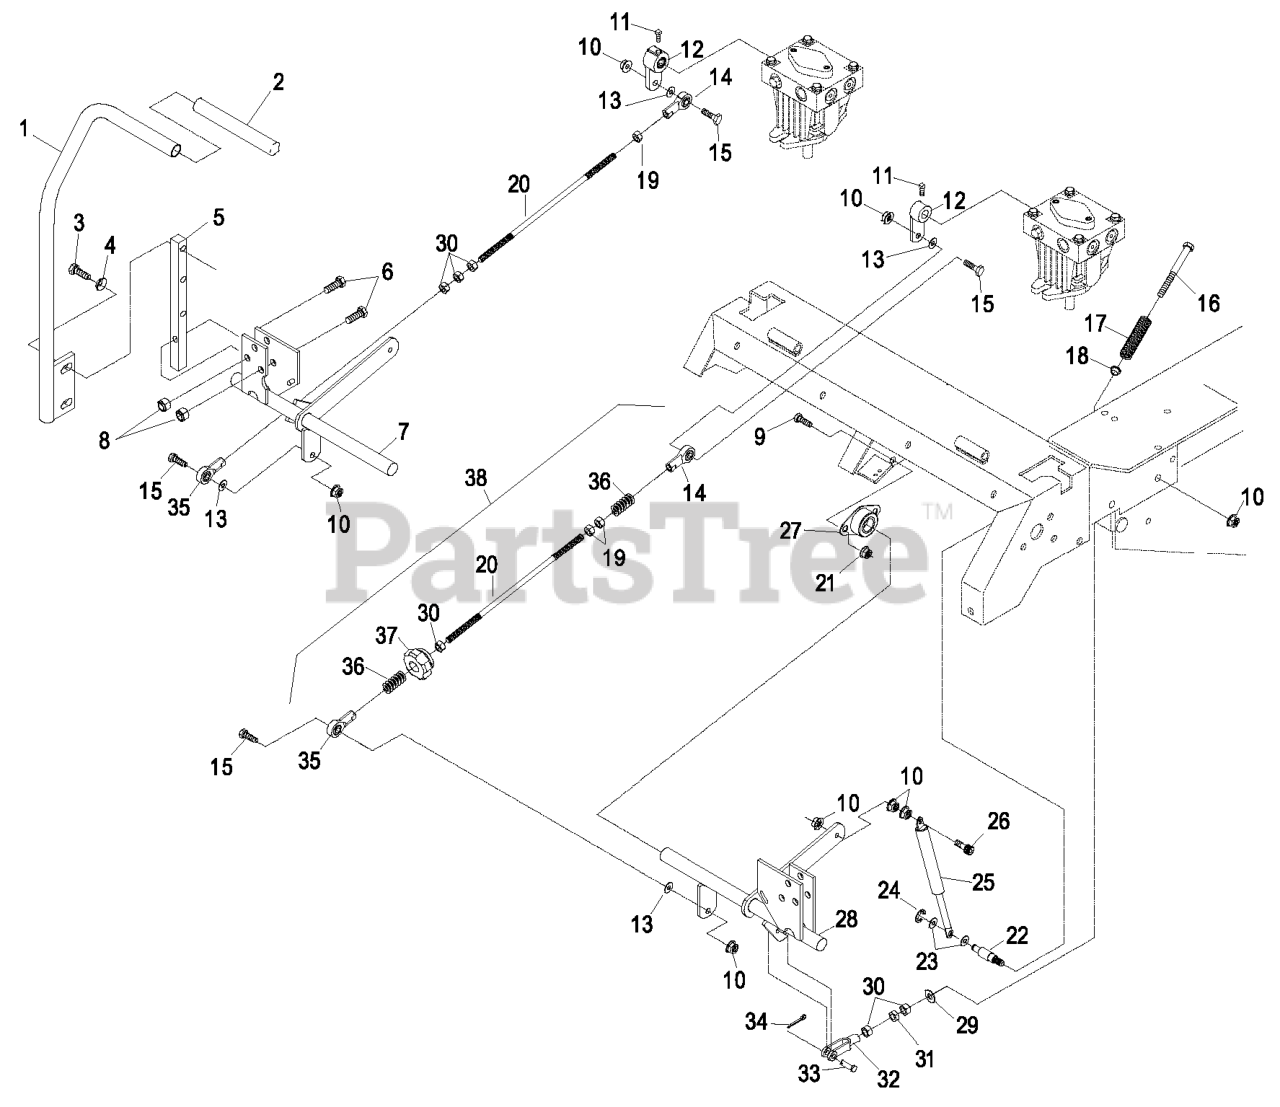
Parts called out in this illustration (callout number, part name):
1	RH LEVER ASM
2	GRIP-CONTROL, MOTION
3	SCREW-HH
4	WASHER-BELLEVILLE
5	ARM-SHAFT, CONTROL
6	SCREW-HH
8	NUT-LOCK, NI
9	SCREW-HH
11	SCREW-SET
12	ARM-CONTROL
13	WASHER-FLAT
14	BALLJOINT-LH
15	SCREW-HH
16	BOLT-RETURN, NEUTRAL
17	SPRING-RETURN, NEUTRAL
18	BUSHING-FLANGED
20	LINK-ROD, TRACKING
21	NUT-HHF, WHIZ
22	PIN-DAMPER
23	WASHER-PLAIN
24	RING-RETAINING, EXT
26	SCREW-HH
27	BEARING-FLANGE, SIDE
29	WASHER-FLAT
30	NUT-HEX
31	NUT-JAM
32	YOKE-ADJUSTABLE
33	PIN-CLEVIS
34	PIN-COTTER
35	BALLJOINT-RH
36	SPRING-COMPRESSION
37	KNOB-TRACKING
